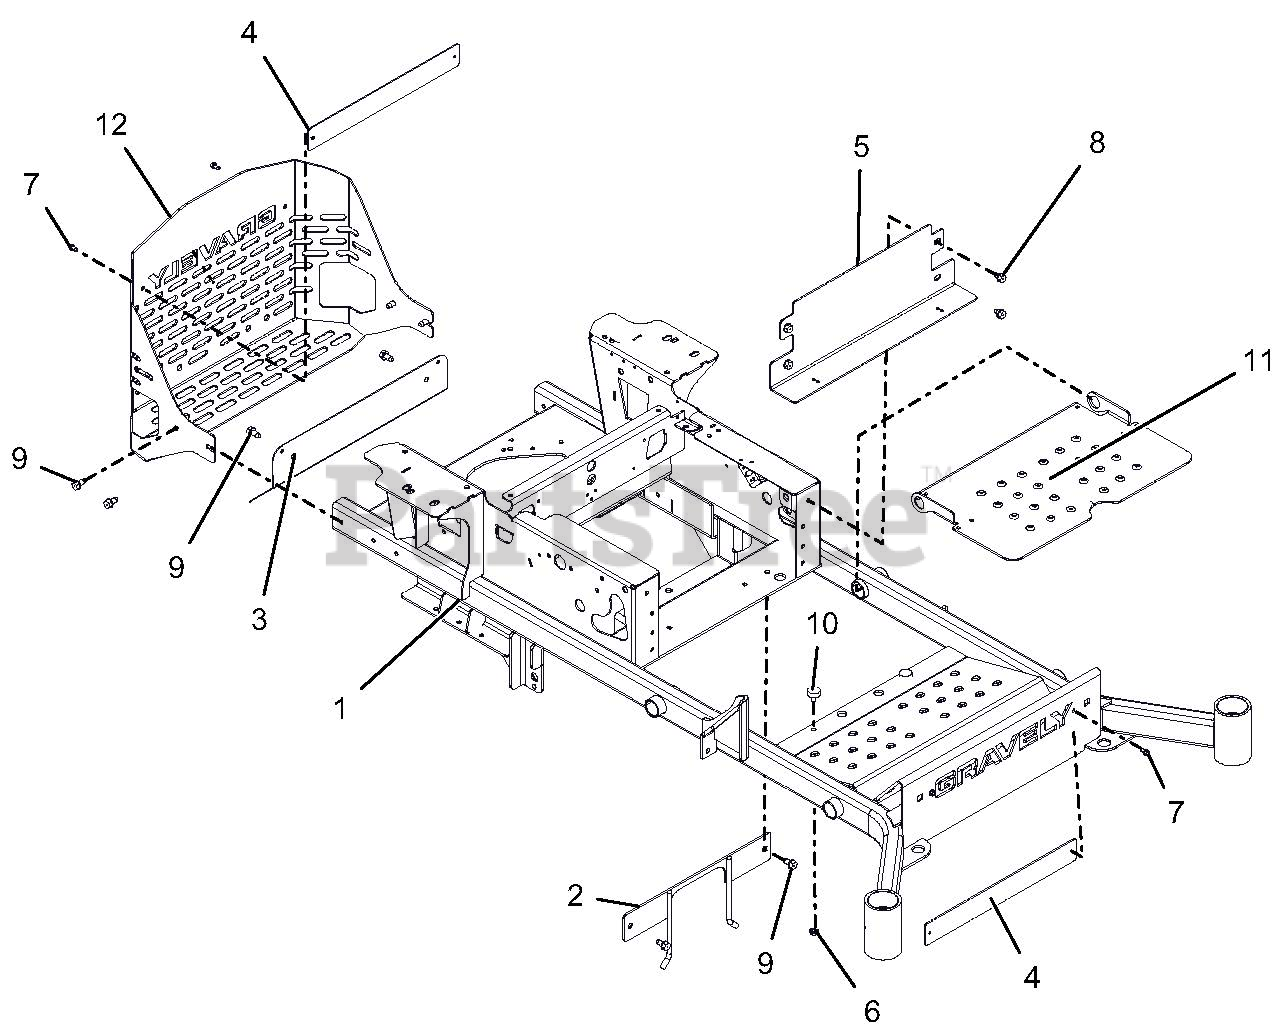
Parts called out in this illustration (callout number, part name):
1	60" MAIN FRAME W/SAFETY DECALS
2	WLDMT, PTO BELT FINGER-BLACK
3	SHIELD, MUFFLER HEAT
4	PLATE, BUMPER 2.00 x 16.50 - BLK
5	PLATE, PT/PT100 KICK-RED
6	@NUT-SPNLK-FLG .312-18 YWZC
7	SCR-TAP .25-20X.50 HWH TR YWZ
8	SCR-TAP .38-16X.50 HWH TR YWZ
9	SCR-TAP .38-16X.75 HWH TR YWZ
10	BUMPER, RUBBER
11	FOOT, PLATE W/SAFETY DECALS
12	REAR BUMPER W/SAFETY DECALS
